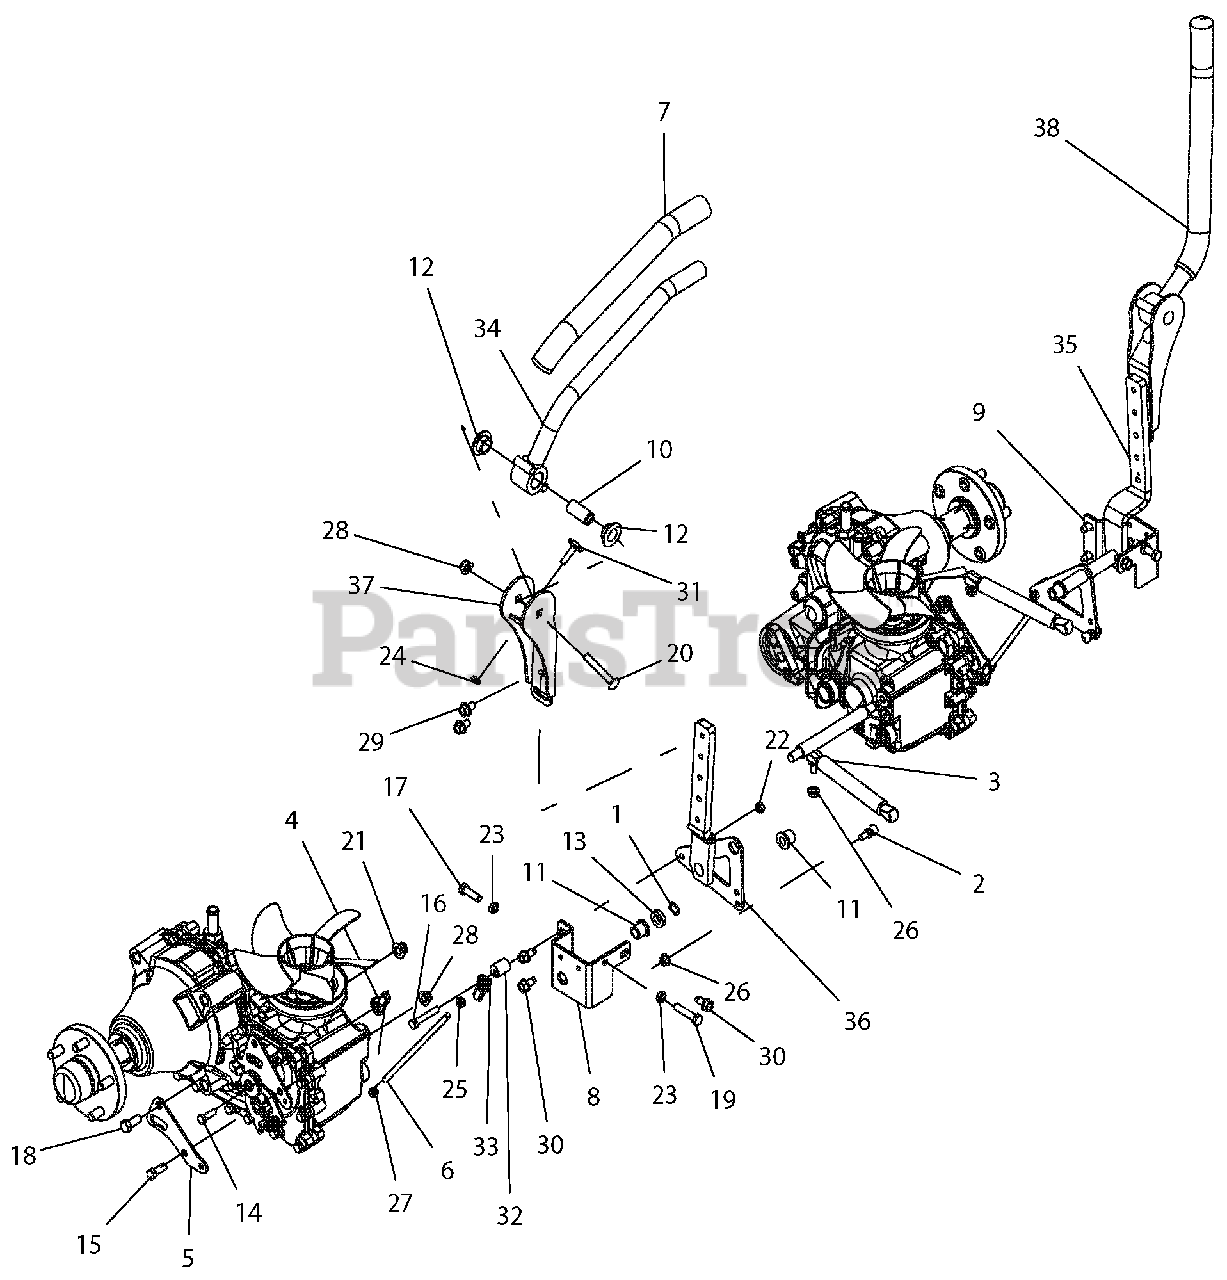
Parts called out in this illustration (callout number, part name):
1	WAVE WASHER .531X.781X.125 FH
2	STUD-BALL
3	DAMPER,
4	ALIGNABALL, 5/16 LH THREAD
5	BRKT., CONTROL MTG-BLACK
6	ROD, STEERING
7	GRIP, HANDLEBAR
8	BRKT, RH CONTROL ARM STOP-RED
9	BRKT, LH CONTROL ARM STOP-RED
10	SPCR, STEERING ARM
11	BHSG-FLG .500X.750X.750X.125
12	BSHG, FLANGE .762 X 1.48 X .44 NYLON
14	BLT-HEX .31-18X1.00 GR5 YWZC
15	BLT-HEX .38-16X1.00 GR5 YWZC
16	BLT-HEX .31-18X2.00 GR5 YWZC
17	BLT-HEX .38-16X1.25 GR5 YWZC
18	BLT-HEX .44-14X1.00 GR5 YWZC
19	BLT-HEX .38-16X1.75 GR5 YWZC
20	BLT-RHDSSQNK .38-16X2.50 G5YZ
21	NUT-LK-NYL-FLG .44-14 YWZC
22	NUT-LK-CTR .31-18 YWZC
23	NUT, JAM .375-16 YWZC
24	NUT, JAM .312-18 YWZC
25	NUT-JAM
26	NUT, LK-TOP-FLG .312-18 YWZC
27	NUT, JAM -LH .31-24 YWZC
28	NUT-LK-NYL-FLG .38-16 YWZC
29	BLT-SERHFWH .38-16X.62 YWZC
30	SCR-TAP .38-16X.75 HWH TR YWZ
31	BUMPER, STUD MOUNTED
32	ECCENTRIC
33	ALIGNABALL, 5/16 RH THREAD
34	WLDMT, RH STEERING ARM
35	WLDMT, LH LOWER CONTROL ARM
36	WLDMT, RH LOWER CONTROL ARM
37	MOUNT, STEERING ARM, ADJUSTABLE-BLACK
38	WLDMT, LH STEERING ARM
